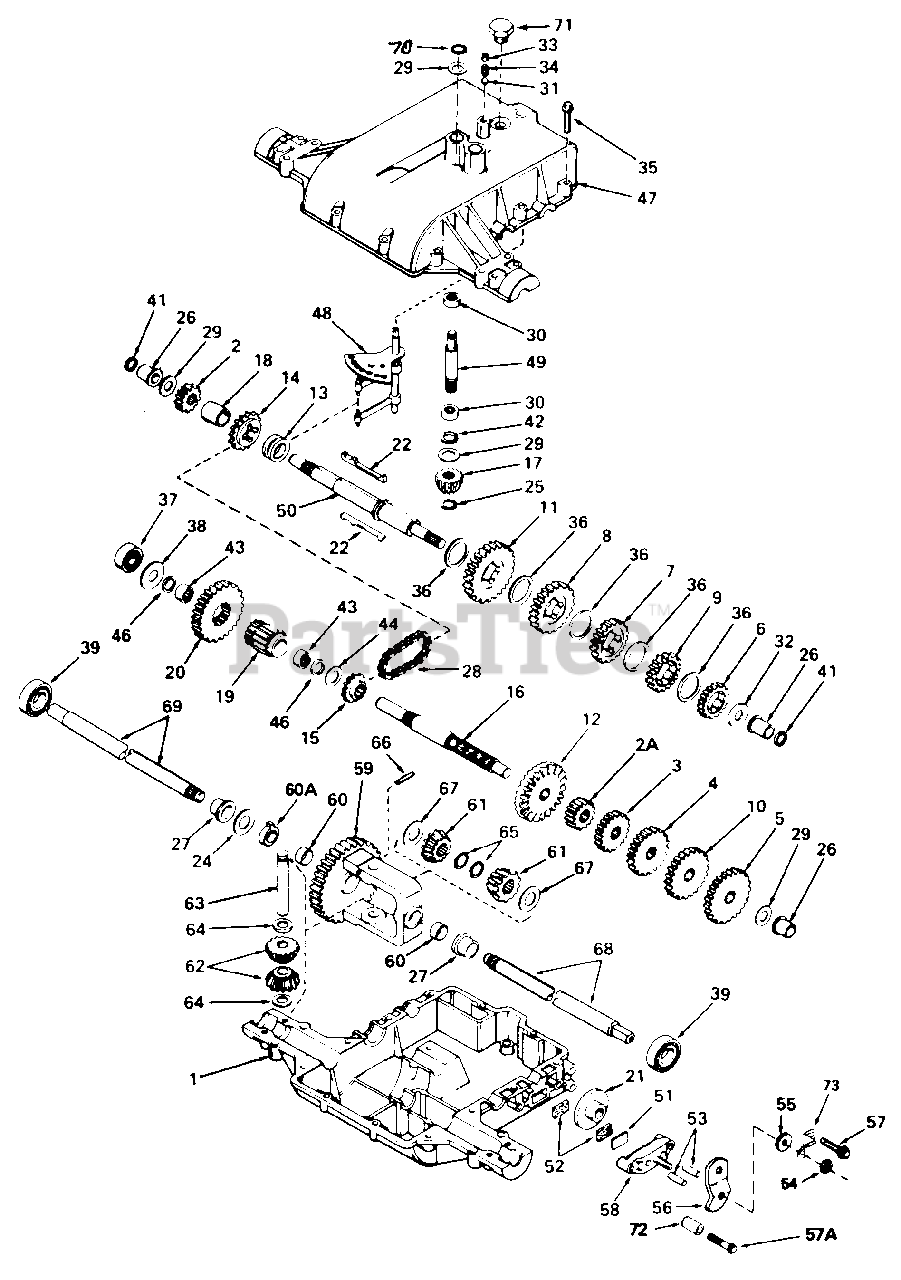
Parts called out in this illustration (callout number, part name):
1	Case, Transaxle
2	Gear, Spur (15 teeth)
2A	Gear, Spur (12 teeth)
3	Gear, Spur (20 teeth)
4	Gear, Spur (25 teeth)
5	Gear, Spur (30 teeth)
6	Gear, Spur (20 teeth)
7	Gear, Spur (25 teeth)
8	Gear, Spur (30 teeth)
9	Gear, Spur (22 teeth)
10	Gear, Spur (28 teeth)
11	Gear, Spur (37 teeth)
12	Gear, Bevel (42 teeth)
13	Collar, Shift
14	Sprocket (18 teeth)
15	Sprocket (9 teeth)
16	Shaft, Counter
17	Bevel Pinion, Input
18	Spacer
19	Pinion, Output
20	Gear, Output
21	Disk, Brake
22	Key
24	Washer
25	Ring, Retaining
26	Bushing, Flanged
27	Bushing, Flanged
28	Chain, Roller (No. 41 Chain, 24 Links)
29	Washer, Thrust
30	Bearing, Needle
31	Ball, Steel
32	Washer, Thrust
33	Screw, Set, 3/8-16 x 3/8
34	Spring
35	Screw, Hex Hd. Thread Forming, 1/4-20 x 11/4
36	Washer, Thrust
37	Bearing, Ball
38	Washer, Flat
39	Bearing, Ball
41	Ring, Square Cut
42	Ring, Square Cut
43	Bearing, Needle
44	Washer, Flat
46	Ring, Square Cut
47	Cover, Transaxle
48	Rod & Fork Ass'y., Shift
49	Shaft, Input
50	Shaft, Brake
51	Plate, Brake Pad
52	Pad, Brake
53	Pin, Dowel
54	Locknut, 5/16-24
55	Washer, Flat
56	Lever, Brake
57	.Screw, Hex Hd. Thread Forming, 1/4-20 x 11/4
57A	Screw, Hex Hd. Thread Forming, 1/4-20 x 21/4
58	Holder, Brake Pad
59	Gear Ass'y., Differential
60	Bushing
60A	Bushing
61	Gear, Bevel
62	Pinion, Bevel
63	Pin, Drive
64	Washer, Thrust
65	Ring, Retaining
66	Pin, Roll
67	Washer, Thrust
68	Axle (15-1/4" Long)
69	Axle (13-3/8" Long)
70	Ring, Retaining
71	Plug, Hex Hd., 9/16-18 Thread
72	Spacer
73	Bracket, Brake Lever
